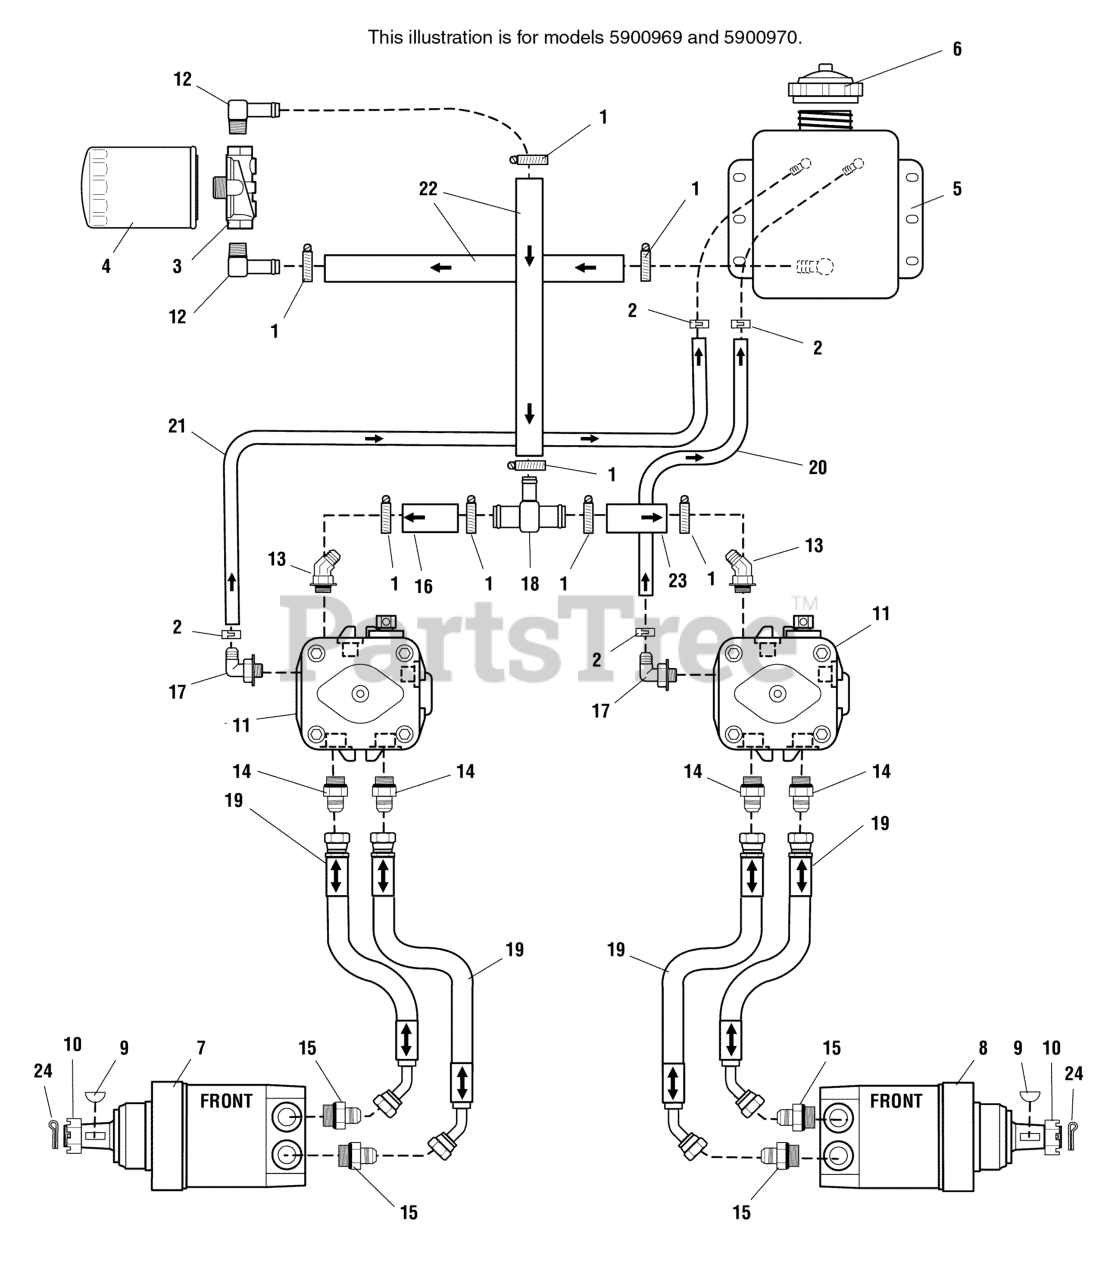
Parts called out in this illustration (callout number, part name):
1	CLAMP, #10 HOSE STAINLESS
2	CLAMP, HOSE
3	FILTER HEAD
4	FILTER, HYDRAULIC, SERVICE PART (PKG)
5	KIT, TANK HYDRAULIC, 3QT W/ FITTINGS
6	CAP, HYDRAULIC RESERVOIR
7	* MOTOR, WHEEL REAR PORT LH 15CI
8	* MOTOR, WHEEL REAR PORT RH 15CI
9	KEY
10	CASTLE NUT
11	** HYDRAULIC PUMP W/ FAN (SV)
11	7" FAN HUB ASSEMBLY (SV)
11	KIT, OVERHAUL SEAL
11	SEAL, OUTPUT SHAFT, 17 X 40 X 7 (SV)
12	FITTING, 1/2NPT-5/8" HOSE, 90 DEG
13	FITTING, 5/8 TUBE TO #8 O-RING, 45 ELBOW
14	ADAPTER, HYDRAULIC
15	ADAPTER, HYDRAULIC
16	HOSE, 5/8 PUSH-LOCK, 6.00"
17	ADAPTER, 90 DEG, 9/16-3/8 BARB
18	TEE, HYDRAULIC, BEADED HOSE, 5/8 X 5/8 X 5/8
19	HOSE ASSEMBLY, (33)
20	HOSE, 3/8" PUSH-LOCK, 12.00"
21	HOSE, 3/8" PUSH-LOCK, 17.50"
22	HOSE, 5/8" PUSH-LOCK, 11.50"
23	HOSE, 5/8" PUSH-LOCK, 8.50"
24	COTTER PIN
